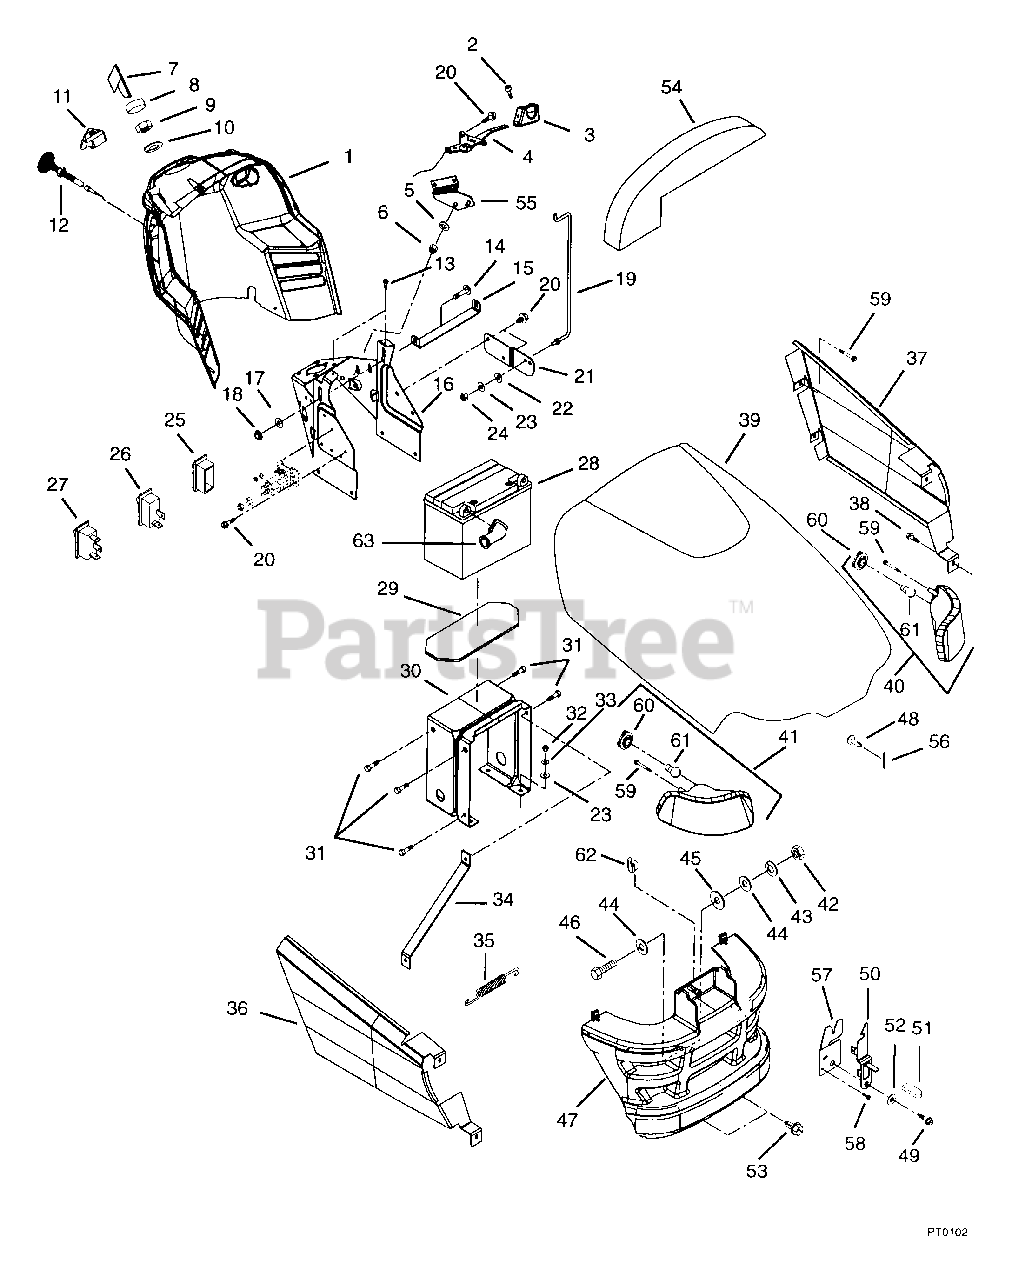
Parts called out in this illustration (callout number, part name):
1	DASH
2	SCR-SET 10-24X.38 UNC-3A
3	KNOB - THROTTLE
4	THROTTLE CONTROL- TEC/B&S
4	THROTTLE CONTROL- 15 KOHLER
4	THROTTLE CONTROL-B&S
4	CABLE, THROTTLE
5	WSHR-FL-STL .323X.625X.062 PL
6	NUT-LK-CTR .250-20 PL
7	KEY -W/CAP
8	CAP - IGNITION SWITCH
9	NUT- PANEL .562-24 GRECO
10	WSHR-LK-INT .563X.040 PL
11	PTO KNOB/ SWITCH ASSY
12	CHOKE CABLE
13	SCR-TAP 10-24X.375 CRPH 1A
14	BLT-RDHDSQNK .312-18X.62 PL
15	HOLDDOWN - BATTERY
16	SUPPORT - DASH - TOP
17	WSHR-FL-STL .323X.625X.062 PL
18	NUT-LK-NYL.312-18 PL
19	ROD - HOOD PROP
20	SCR-TAP .250-20X.37 HWH PL TR
21	MOUNT - PROP ROD
22	WAVE WASHER .390X.655X.110
23	WSHR-FL-STL.312X.734X.065PL
24	NUT-LK-CTR .250-20 PL
25	COVER - SWITCH
26	SWITCH - LIGHT
27	SWITCH - CRUISE
28	BATTERY W/TUBE
29	RUBBER PAD
30	SUPPORT DASH BASE
31	SCR-TAP .312-18X.50 HWH PL TR
32	NUT-HEX .312-18
33	WSHR-LK .312X.097 PL HVY
35	SG-TENS .035X.45X2.75 WLD 3.5
36	SIDE PANEL- RH
37	SIDE PANEL- LH
38	SCR-TAP 12-16X.500 HI-LOTPHBL
39	HOOD WITH DECALS
40	HEADLIGHT- LH
41	HEADLIGHT- RH
42	NUT-HEX .312-18
43	WSHR-LK .312X.097 PL HVY
44	WSHR-FL-STL .328X1.0X.094 PL
45	WSHR-FL-NYL .390X1.000X.062
46	BLT-HEX .31-18X1.00 PL GR5
47	GRILLE
48	PIN, CLEVIS .243/.248X1.50 YWZ
49	SCR-TAP 12-24X.50 HWH TR BLACK
50	HOOD LATCH
51	GRIP .062 X .375 X 1.000 RE
52	WSHR-FL-STL .281X1.250X.048 BL
53	SCR-TAP .312-18X.50 HWH TR BL
54	BAFFLE- HOOD
55	BRACE-THROTTLE CONTROL
56	PIN-COTR .09X.75 PL
57	LOCATOR- HOOD
58	SCR-TAP 10-12X.50 CRPH PL A BL
59	SCR-TAP 10-12X.62 CRPH PL A
60	LAMP SOCKET
61	HEADLIGHT BULB, 1156
62	CLIP-HARNESS TINNERMAN
63	INSULATOR
